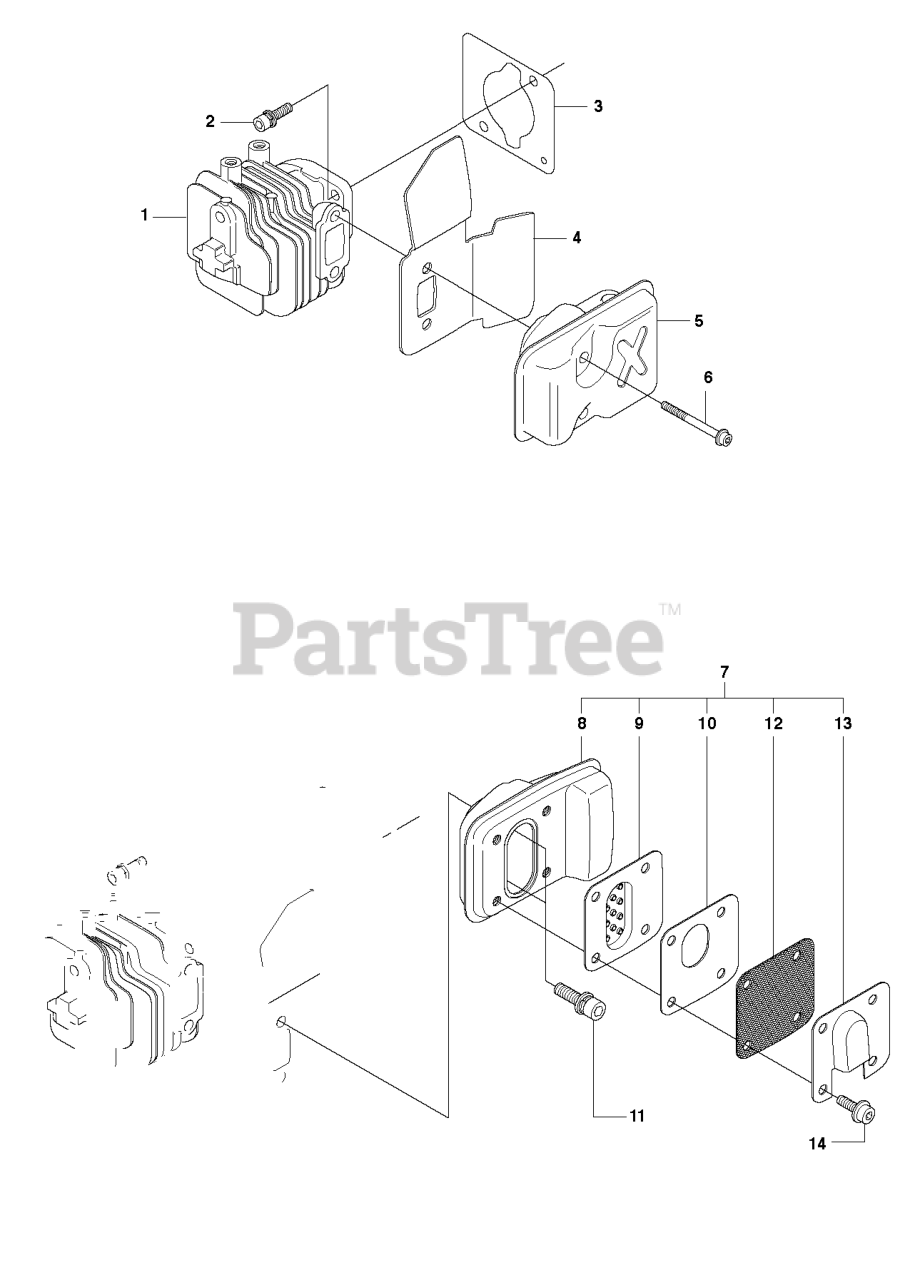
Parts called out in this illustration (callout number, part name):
1	CYLINDER/CARB
3	BASE GASKET
4	HEAT SHIELD/GASKET
7	MUFFLER ASSY
9	BAFFLE PLATE
10	BAFFLE PLATE
12	SPARK ARRESTER
13	EXHAUST DEFLECTOR
